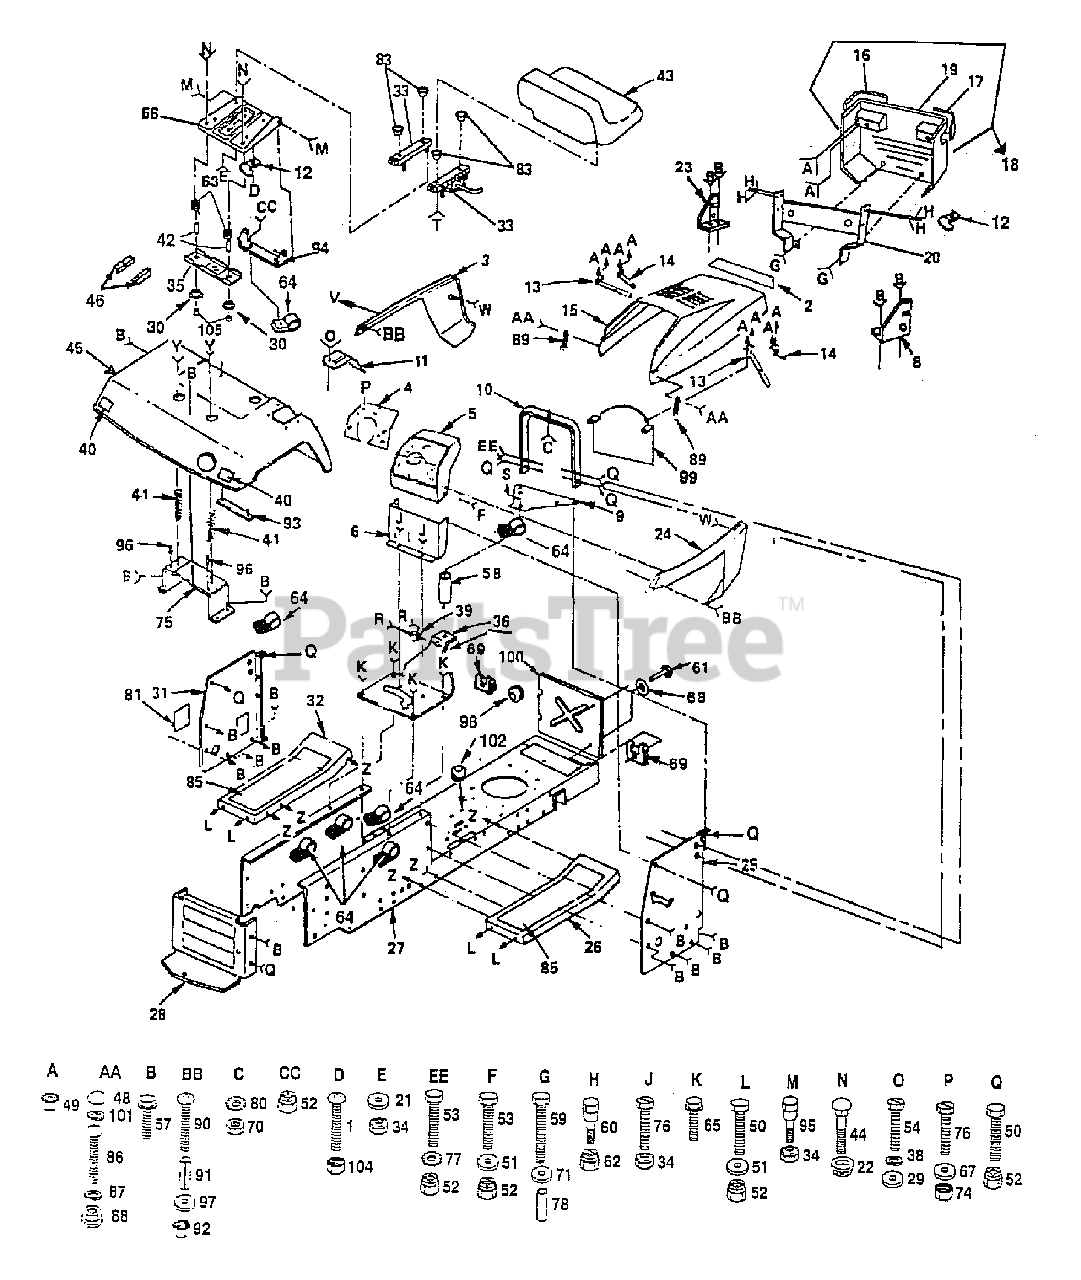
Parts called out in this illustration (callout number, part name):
1	Screw, Slotted Pan Head #10-32 x 1/2
2	Foam, Strip
3	Panel, Side, L.H.
4	Dash, Plate
5	Dashboard
6	Dash, Assembly, Lower
8	Bracket, Assembly, R.H.
9	Plate, Support, Battery
10	Support, Assembly, Dash
11	Console, Shifter
12	Clip, Insulated
13	Strap, Assembly, Hinge, Rear
14	Strap, Assembly, Hinge, Front
15	Hood
16	Lens, L.H.
17	Lens, R.H.
18	Grill Assembly
19	Grill
20	Support Assembly, Grill
21	Washer 11/32 x 1 x 10 Ga.
22	Locknut, Hex, Large Flange 1/4-20 UNC
23	Bracket, Assembly, L.H.
24	Panel, Side, R.H.
26	Footrest, R.H.
28	Drawbar
29	Washer 3/16 x 7/16 x 18 Gauge
30	Bushing, Snap
31	Panel, Dash, L.H.
32	Footrest, L.H.
33	Slide Set, Seat
34	Locknut 5/16-18
35	Bracket, Switch Mount
36	Saddle
38	Washer, Lock #8
39	Bushing, Steering
40	Reflector, Taillight
41	Spring, Compression
42	Spacer, Split 0.28 x 0.88
43	Seat
44	Bolt, Carriage 1/4-20 x 1-1/4
46	Foam, Strip
49	Nut, Hex Keps 1/4-20
50	Bolt, Hex 3/8-16 x 3/4
51	Washer 13/32 x 13/16 x 12 Gauge
52	Nut, Crownlock 3/8-16
53	Bolt, Hex 3/8-16 x 1
54	Screw #8-3/8
57	Screw, Hex Washer Hd. Thread Rolling 3/8-16 x 3/4 Type TT
59	Bolt, Hex 1/4-20 x 2-1/2
60	Bolt, Shoulder 1/4-20
61	Stud 1/4 Turn
62	Nut, Crownlock 1/4-20
63	Spring, Compression
64	Clip, Insulated
65	Screw, Hex Washer Hd. Thd. Forming 3/8-16 x 1/2 Type TT
67	Washer 11/32 x 11/16 x 16 Gauge
68	Retainer 1/4 Turn
69	Receptacle 1/4 Turn
70	Nut, Hex 1/4-20
71	Washer 9/32 x 3/4 x 16 Gauge
74	Nut, Keps 5/16-18
75	Bracket Assembly, Fender
76	Screw, Mach 5/16-18 x 3/4
77	Washer, Lock 3/8 External Tooth
80	Washer, Lock 1/4 Int./External
81	Cover, Access
85	Pad, Footrest
86	Screw, Cross Recess Pan Hd. Machine #10-24 x 1/2
88	Nut, Weld
89	Latch, Hood
90	Screw, Machine CR #10-24 x 1-1/4
91	Spacer, Split #10 x 3/4
92	Nut, Keps #10-24
93	Strap Assembly, Fender
94	Bracket, Pivot, Seat
95	Bolt, Shoulder 5/16-18
97	Washer 7/32 x 1/2 x 18 Gauge
98	Grommet, Split
99	Baffle, Rear Upper
100	Shield, Heat
101	Washer, Snap Cap
104	Nut, Keps #10-32 UNC
105	Cap, Spring, Seat
